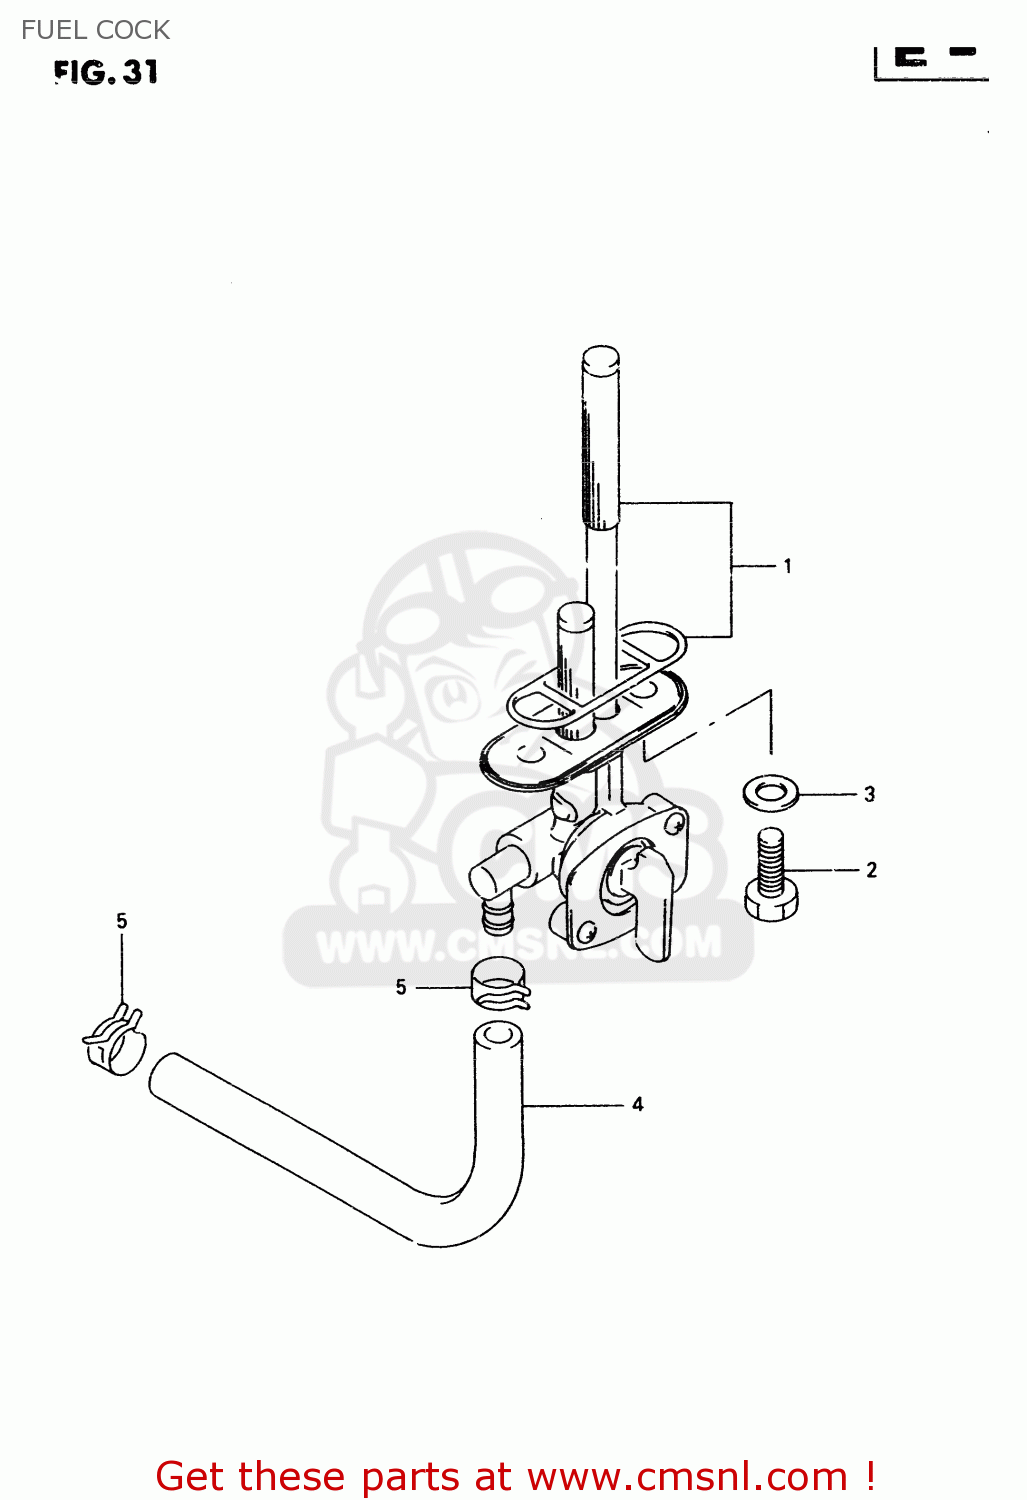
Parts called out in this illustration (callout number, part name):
1	COCK ASSY,FUEL
2	BOLT(6X20)
3	GASKET(6.4X11.5X0.8) (NAS)
4	HOSE(5X10X600)
5	CLIP
